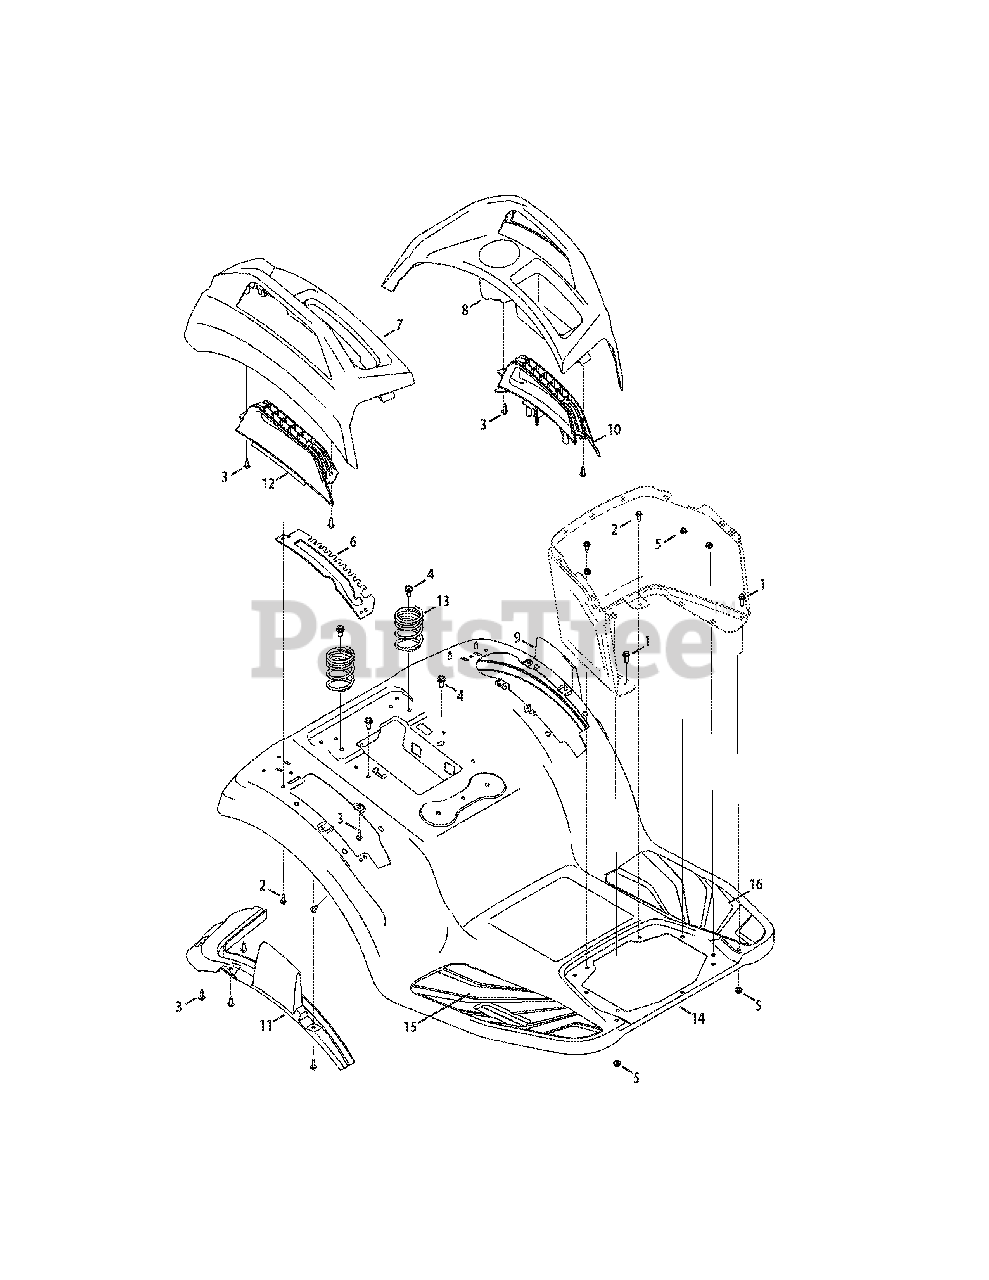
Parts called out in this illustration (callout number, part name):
1	Hex flange Screw, 1/4-20 x .75
2	Screw, M6-1 x .625
3	Screw, 1/4-10 x .75
4	Screw, Self-tapping, 3/8-16, 0.750,
5	Nut, Flange Lock, 1/4-20, Nylon
7	Upper Cover, RH
8	Upper Cover, LH
9	Lower Cover, LH
10	Cover Handle, LH
11	Lower Cover, RH
12	Cover Handle. RH
13	Compression Spring, 2.50 x 3.951 x .207
14	Fender
15	Pad, Foot, RH
16	Pad, Foot, LH
